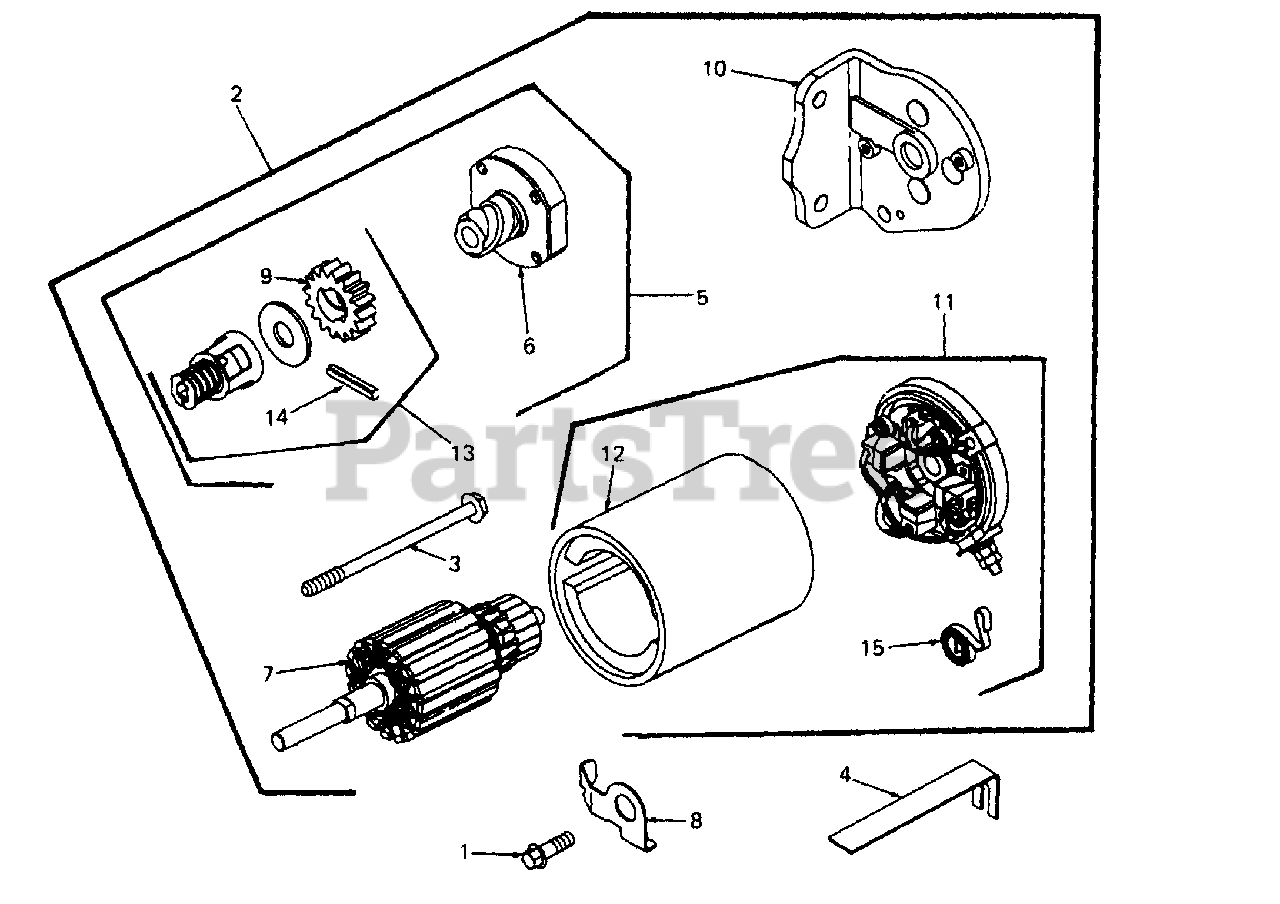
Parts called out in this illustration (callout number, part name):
1	Screw, Hex
2	Motor, Starter Assy
3	Screw, Hex
4	Strap, Starter
5	Starter Drive Group
6	Clutch Assy
7	Armature Assy
8	Clip, Wire
9	Gear, Starter
10	Drive End Cap Assy
11	Cap Assy, Commutator End
12	Housing Assy
13	Kit, Gear
14	Pin, Roll
15	Brush, Spring
